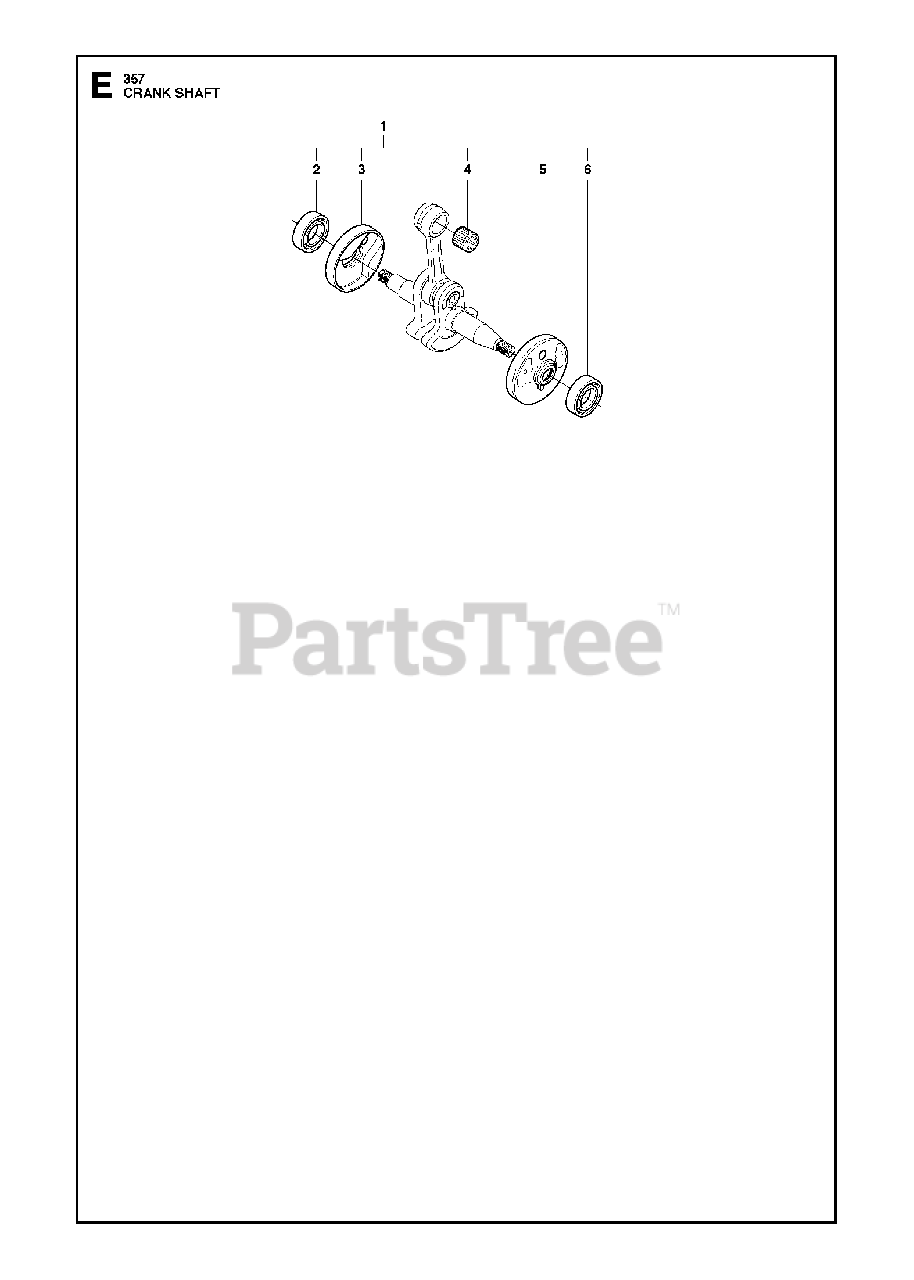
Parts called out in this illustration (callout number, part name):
1	CRANKSHAFT
2	BALL BEARING-6202-C3 SKF
3	CUP
4	SUPPORT BUSHING
5	CUP
6	BALL BEARING-6202-C3 SKF
